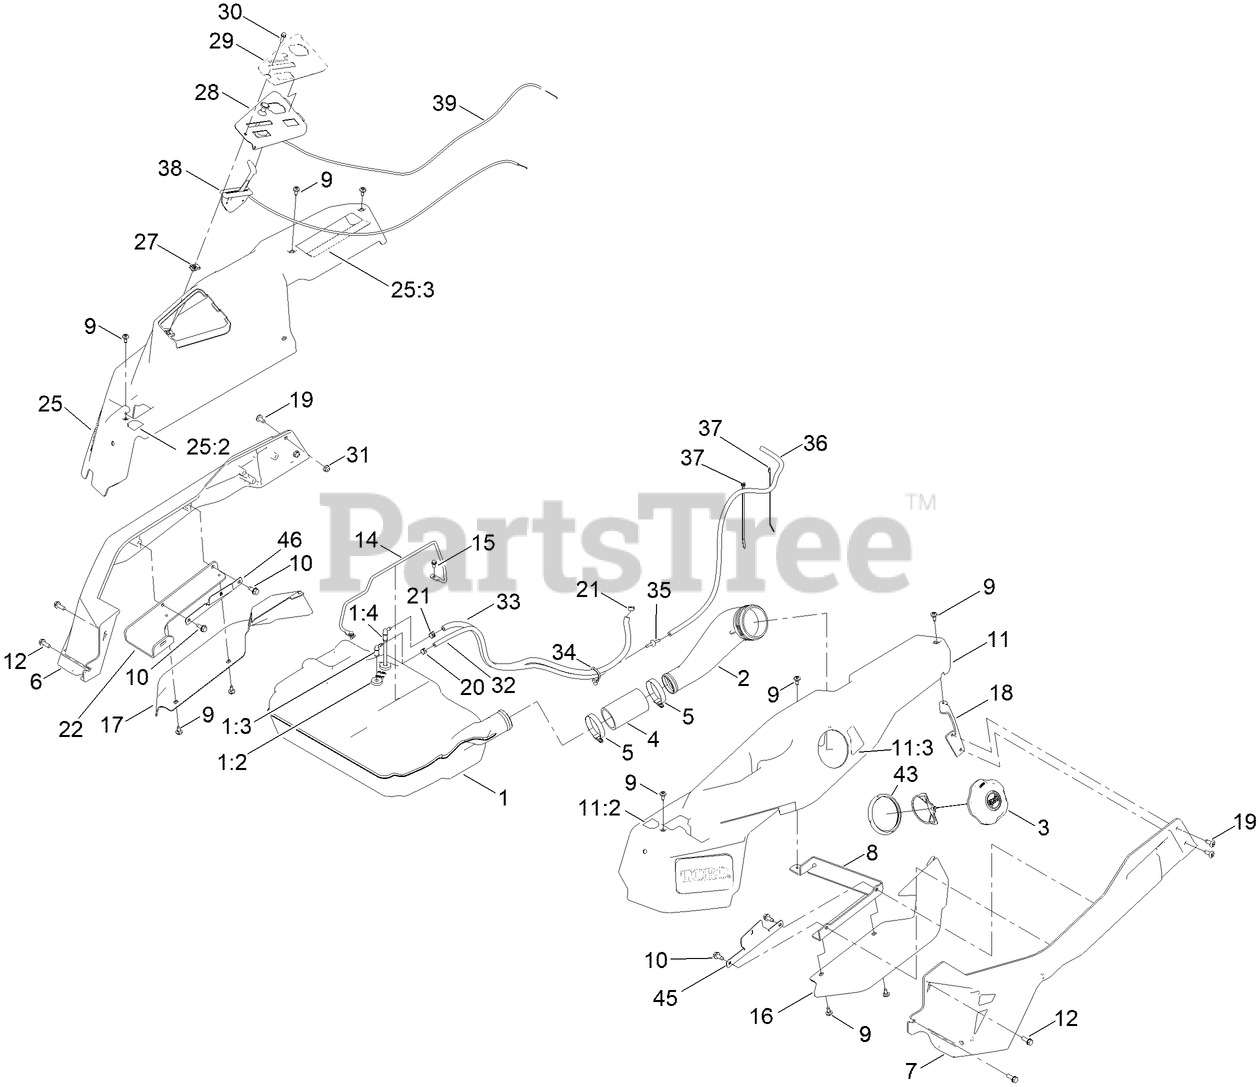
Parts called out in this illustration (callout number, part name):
1	TANK-FUEL ASM
1:2	BUSHING
1:3	FITTING-ELBOW 90
1:4	FITTING - PICKUP, FUEL
2	NECK-FILLER, FUEL
3	CAP-FUEL, RATCHETING
4	HOSE-FILLER, FUEL
5	CLAMP-HOSE
6	CAST-TUBE, RH [RED]
7	CAST-TUBE, LH [RED]
8	MOUNT-POD BRACKET LH
9	SCREW-SHOULDER
10	SCREW-HWHTF
11	POD ASM - LH W/DECALS
11:2	DECAL-CONTROL LEVER, LH
11:3	DECAL-FUEL FILL
12	SCREW-TAPTITE
14	ROD-HOLD DOWN
15	SCREW-HWH
16	FENDER-TIME CUTTER, LH
17	FENDER-TIME CUTTER, RH
18	BRACKET-REAR POD, LH
20	CLAMP-HOSE
21	CLAMP-HOSE
22	BRACKET-MR SPRING
25	POD ASM - RH , MR W/DECALS
25:2	DECAL-CONTROL LEVER, RH
25:3	DECAL - MYRIDE
28	PANEL-CONTROL
29	DECAL - CONTROL PANEL W/OUT HOUR METER
30	SCREW-HWH
31	NUT-HF
32	HOSE-FUEL
33	HOSE-FUEL
34	CLIP-TIE
35	ADAPTER ORIFICE
36	HOSE-LP
37	TIE-CABLE
38	CABLE-THROTTLE
39	CABLE-CHOKE
43	RING-RETAINING
45	BRACKET-ALIGNMENT, POD LH
46	BRACKET- ALIGNMENT, POD RH MR
